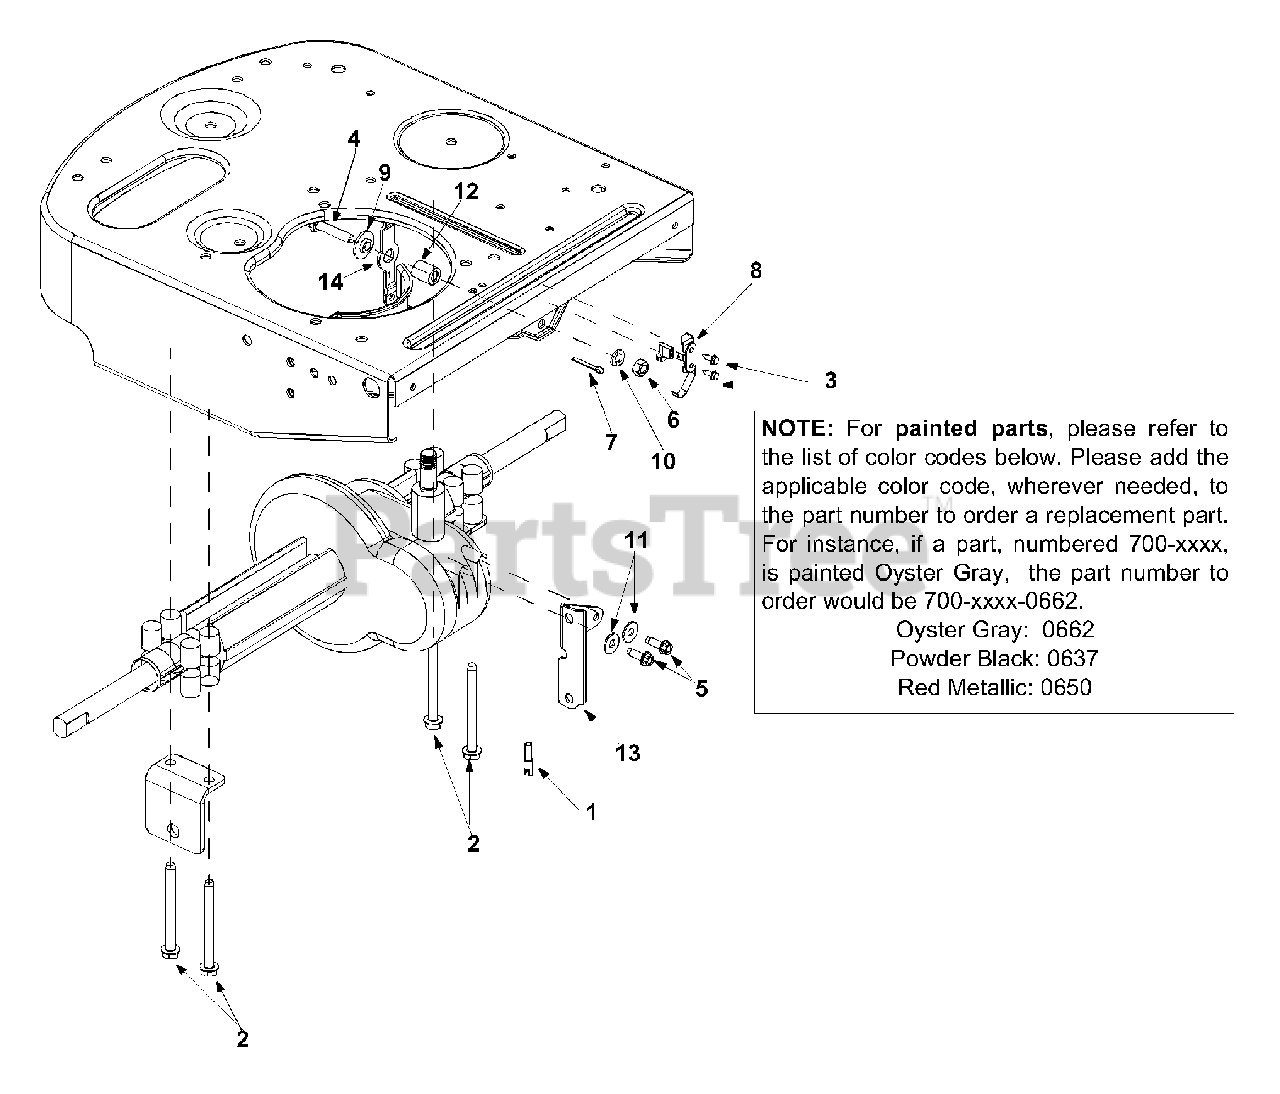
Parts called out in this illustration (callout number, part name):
1	Harness Assembly Adapter
2	Hex TT Screw 5/16-18 x 3.50
3	Hex Washer Head Self-Tap. Scew
4	Hex Screw 5/16-18 x 1.5 Gr. 5
5	Thd. Forming Scr. 1/4-20x .75
6	Hex Nut 5/16-18
8	Insulator Nut Plate
9	Shoulder Bushing
10	Lock Washer 5/16
11	Flat Washer
12	Spacer
